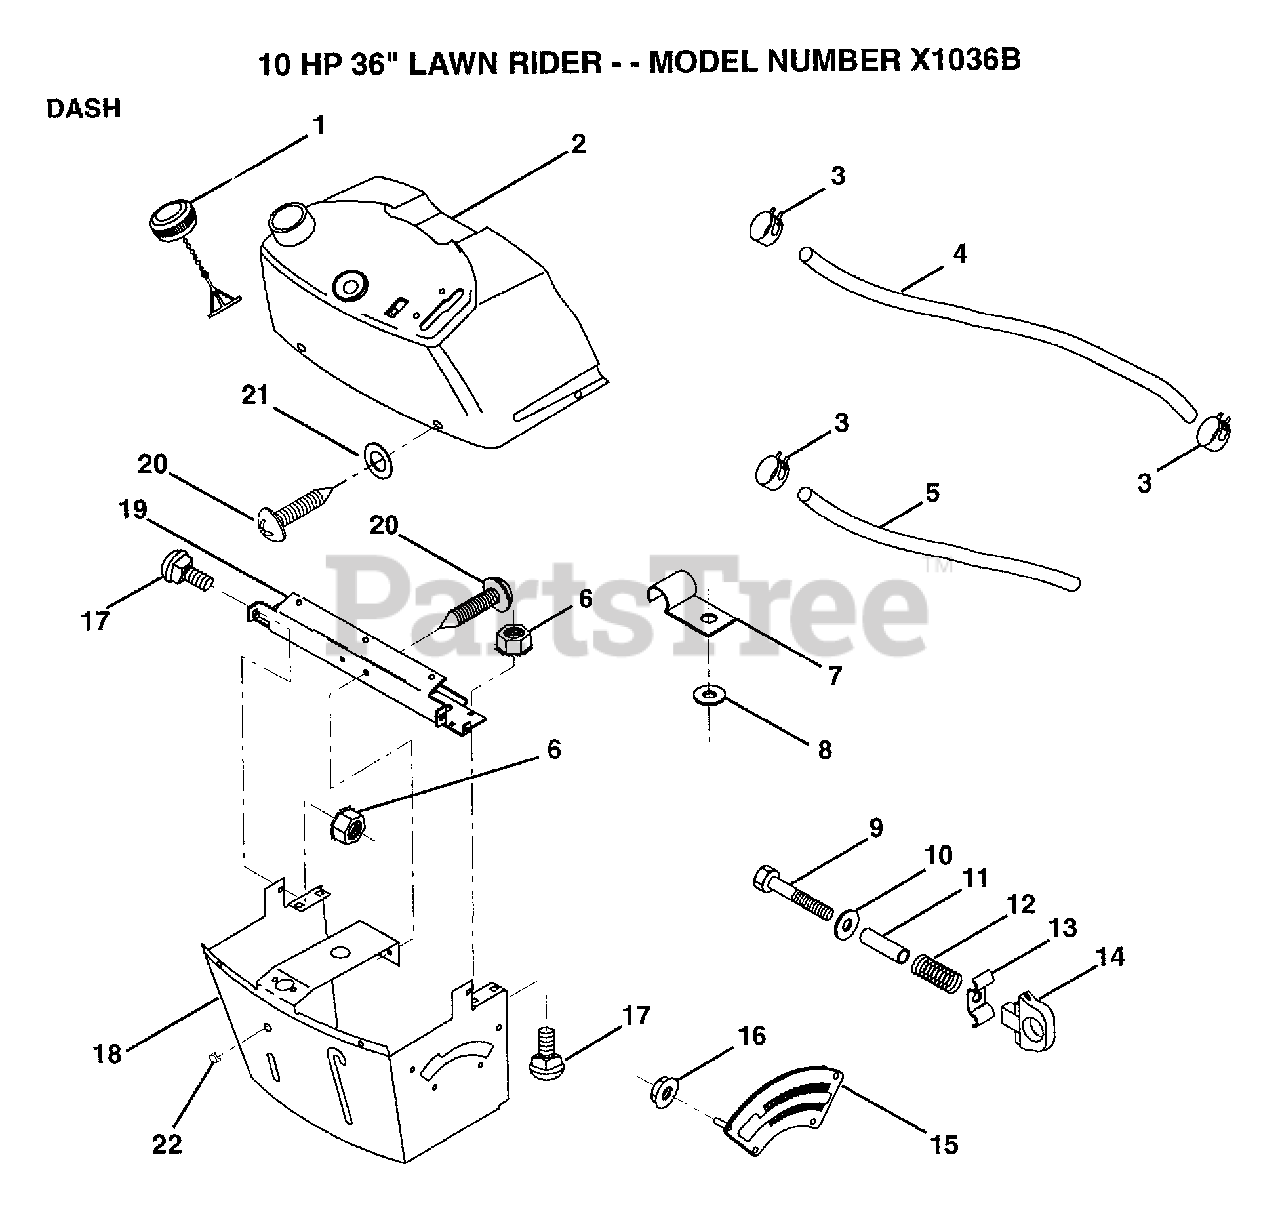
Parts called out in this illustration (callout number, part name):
3	HOSE CLAMP
5	FUEL LINE T
6	NUT
7	CLIP T
8	WASHER PM
9	BOLT
11	SPACER SPLIT
12	SPRING M
13	"KNOB,HGT RETAINER"
14	KNOB
15	ADJUSTER QUAD
16	NUT
17	BOLT
18	SUPT ASSY DASH
19	CROSS BRACE
22	PLUG DOME
